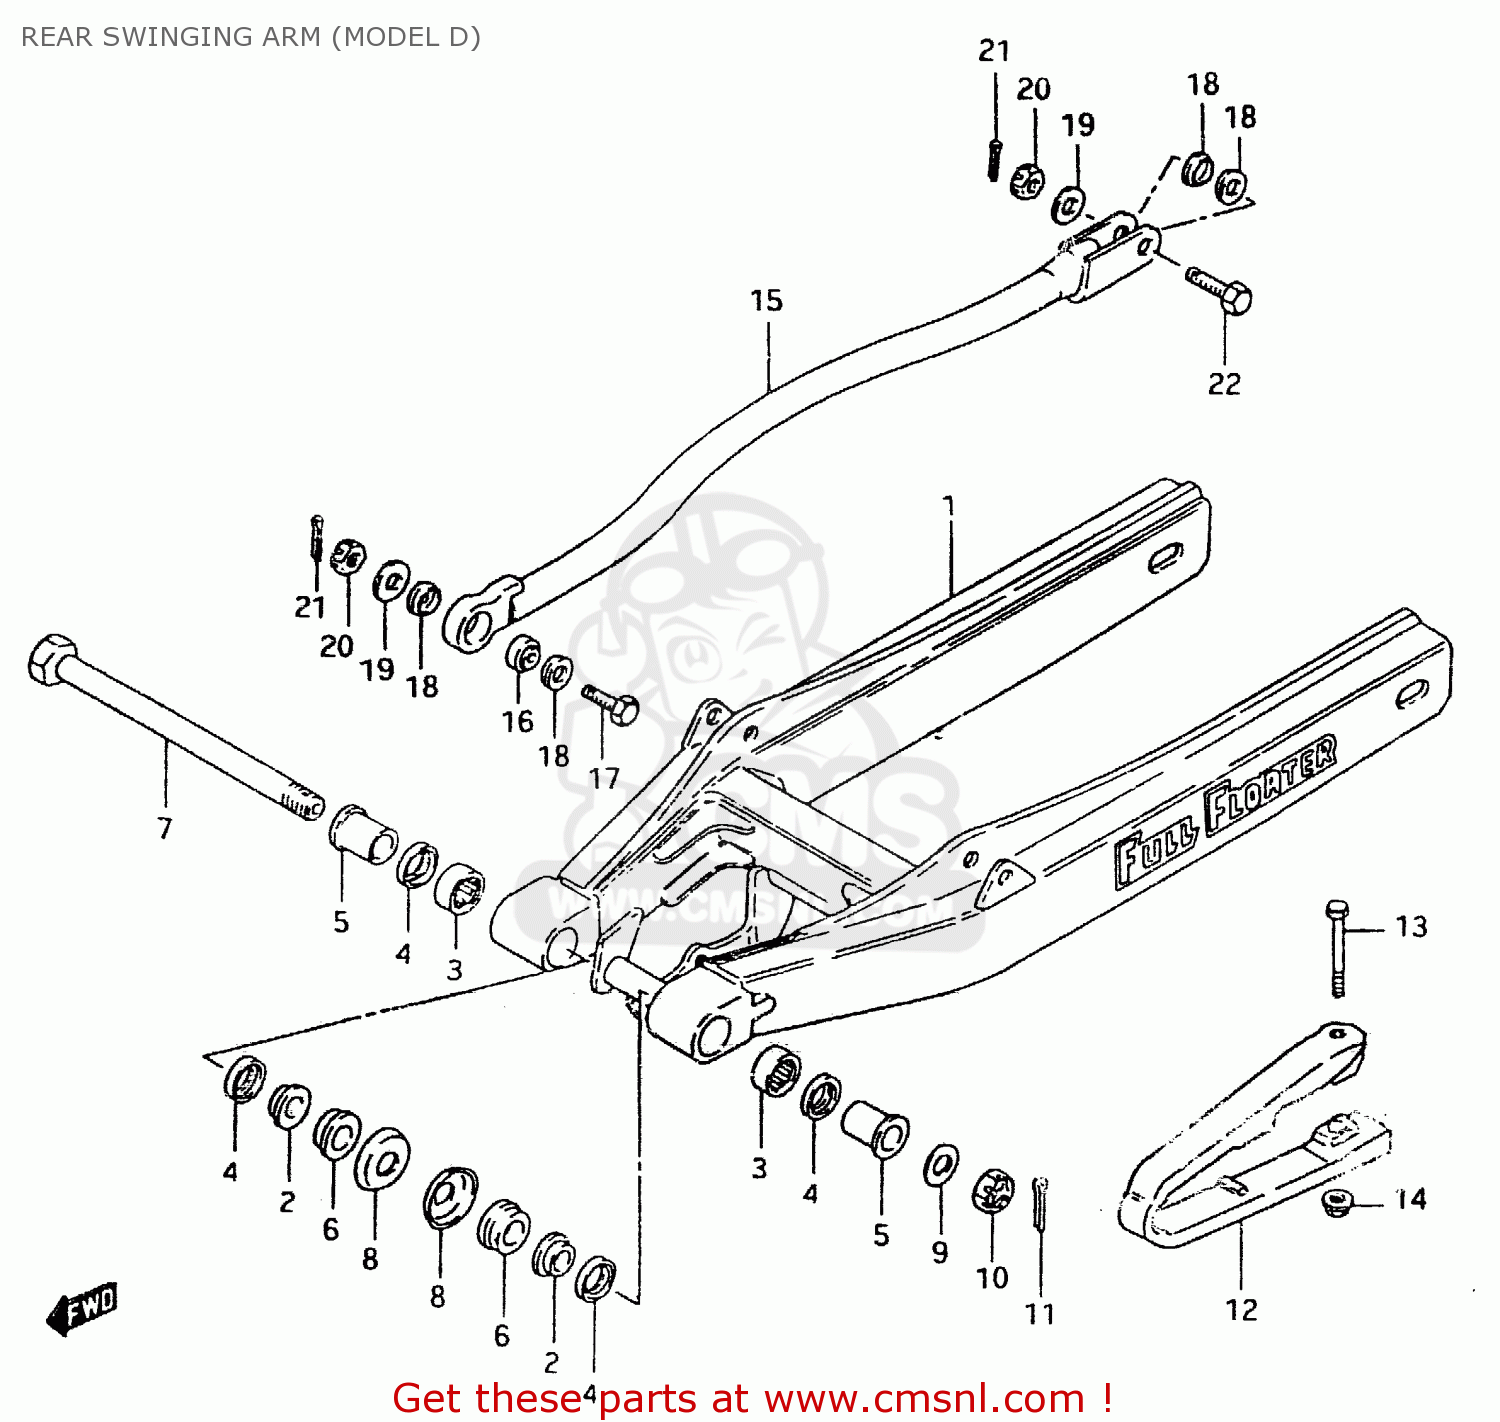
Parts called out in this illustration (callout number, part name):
1	SWING ARM ASSEMBLY,REAR
2	BUSHING,REAR SWING ARM PIVOT
3	BEARING(20X27X20)
4	OIL SEAL
5	SPACER,RR SWGARM PIVOT
6	SPACER,RR SWGARM PIVOT INNER
7	SHAFT,RR SWINGINGARM PIVOT
8	COVER,RR SWGARM DUST SEAL
9	WASHER
10	NUT 14MM
11	COTTER PIN
12	BUFFER,CHAIN TOUCH DEFENSE
13	BOLT(6X70)
14	NUT
15	TORQUE LINK SET,RR
16	SPHERICAL BEARING,TORQUE
17	BOLT 8X28
18	19
19	WASHER
20	NUT 8MM
21	PIN 20X20
22	BOLT 8X29.5
